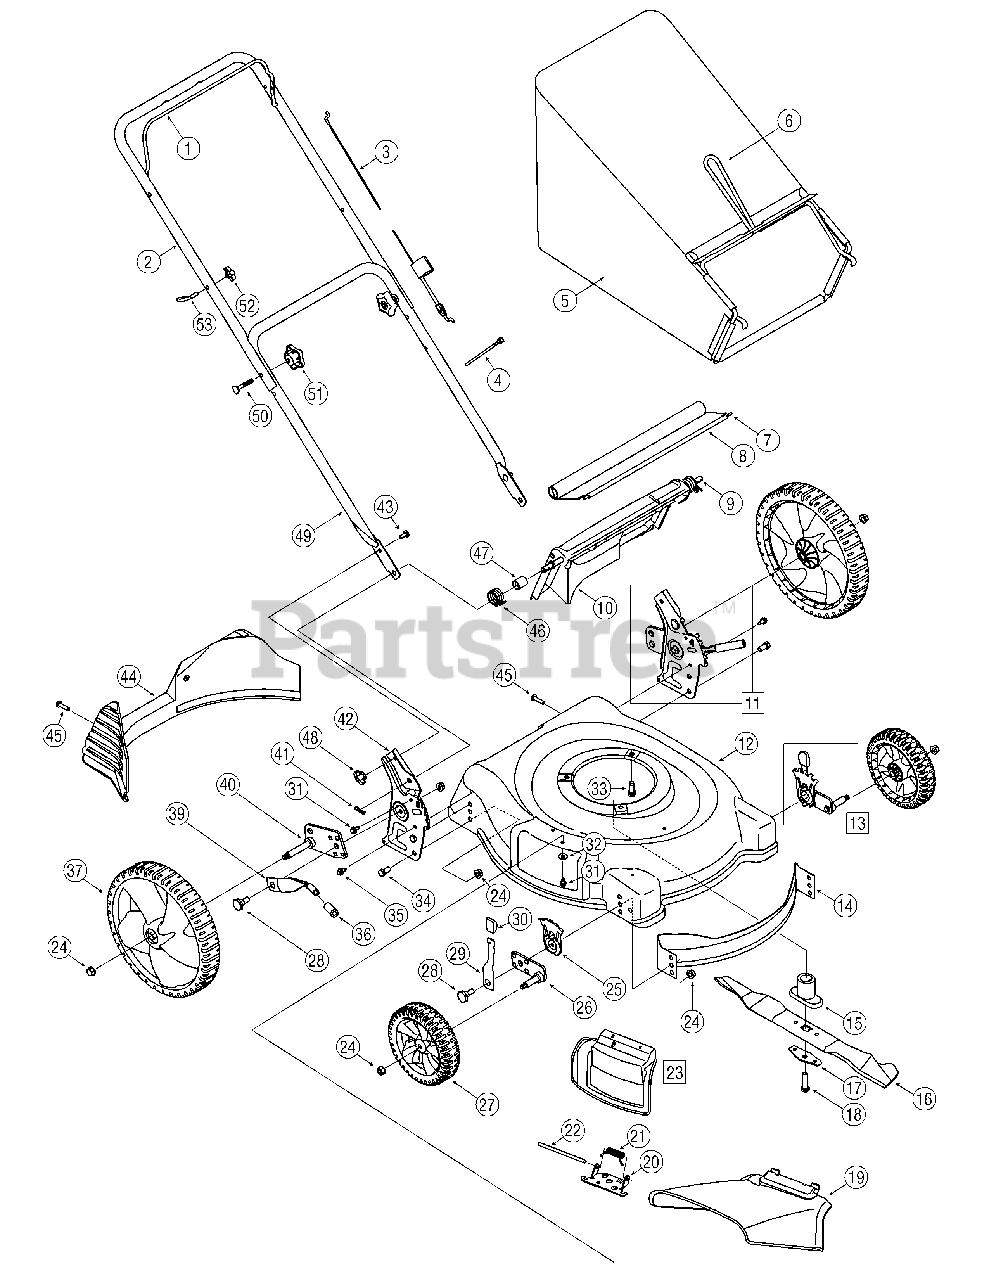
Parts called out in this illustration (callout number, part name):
3	Control Cable, 40" Model 546 & 549
3	Control Cable, 53" Model 543
4	Cable Tie
5	Grass Bag Assembly
7	Trailshield Wire
8	Trailshield
9	Pivot Rod
10	Rear Discharge Door
11	Rear Handle Bracket Assy. - LH
11	Rear Handle Bracket Assy. - RH
13	Front Height Adj. Assy-RH
14	Front Baffle
15	Blade Adapter
15	Blade Adapter 25mm
16	21-inch Mulching Blade
17	Bell Blade Support
18	Hex Screw, 3/8-24 x 2.5
19	Side Discharge Chute
20	Deflector Chute Adaptor
21	Torsion Spring
22	Hinge Pin
23	Hinged Mulch Plug Assembly
24	Flange Lock Nut 3/8-16
25	Height Adjustment Plate
26	Front Pivot Arm Assembly - RH
26	Front Pivot Arm Assembly - LH
27	Front Wheel, 8 x 1.8 Gray
28	Shoulder Screw, .5D x .434
29	Front Spring Lever
30	Height Adjust Knob
31	TT Screw, 1/4-20 x .500
32	Bell Washer
33	TT Screw, 3/8-16 x 1.0
34	Hex Screw, 3/8-16 x .75
35	TT Screw, 1/4-20 x .625
36	Foam Grip
37	Rear Wheel, 12 x 1.8 Gray Bar
38	Eye Bolt
39	Rear Hi-Wheel Spring
40	Rear Pivot Arm Assy - RH
40	Rear Pivot Arm Assy - LH
41	Hairpin Clip
42	Handle Bracket Assy -RH
42	Handle Bracket Assy - LH
43	Carriage Bolt ,1/4-20 x .75
44	Rear Baffle
45	Screw HL, 1/4-15 x 1.00
46	Torsion Spring - RH
46	Torsion Spring - LH
47	Spacer
48	Wing Nut
50	Carriage Bolt, 5/16-18 x 2
51	Star Knob
52	Handle Knob
